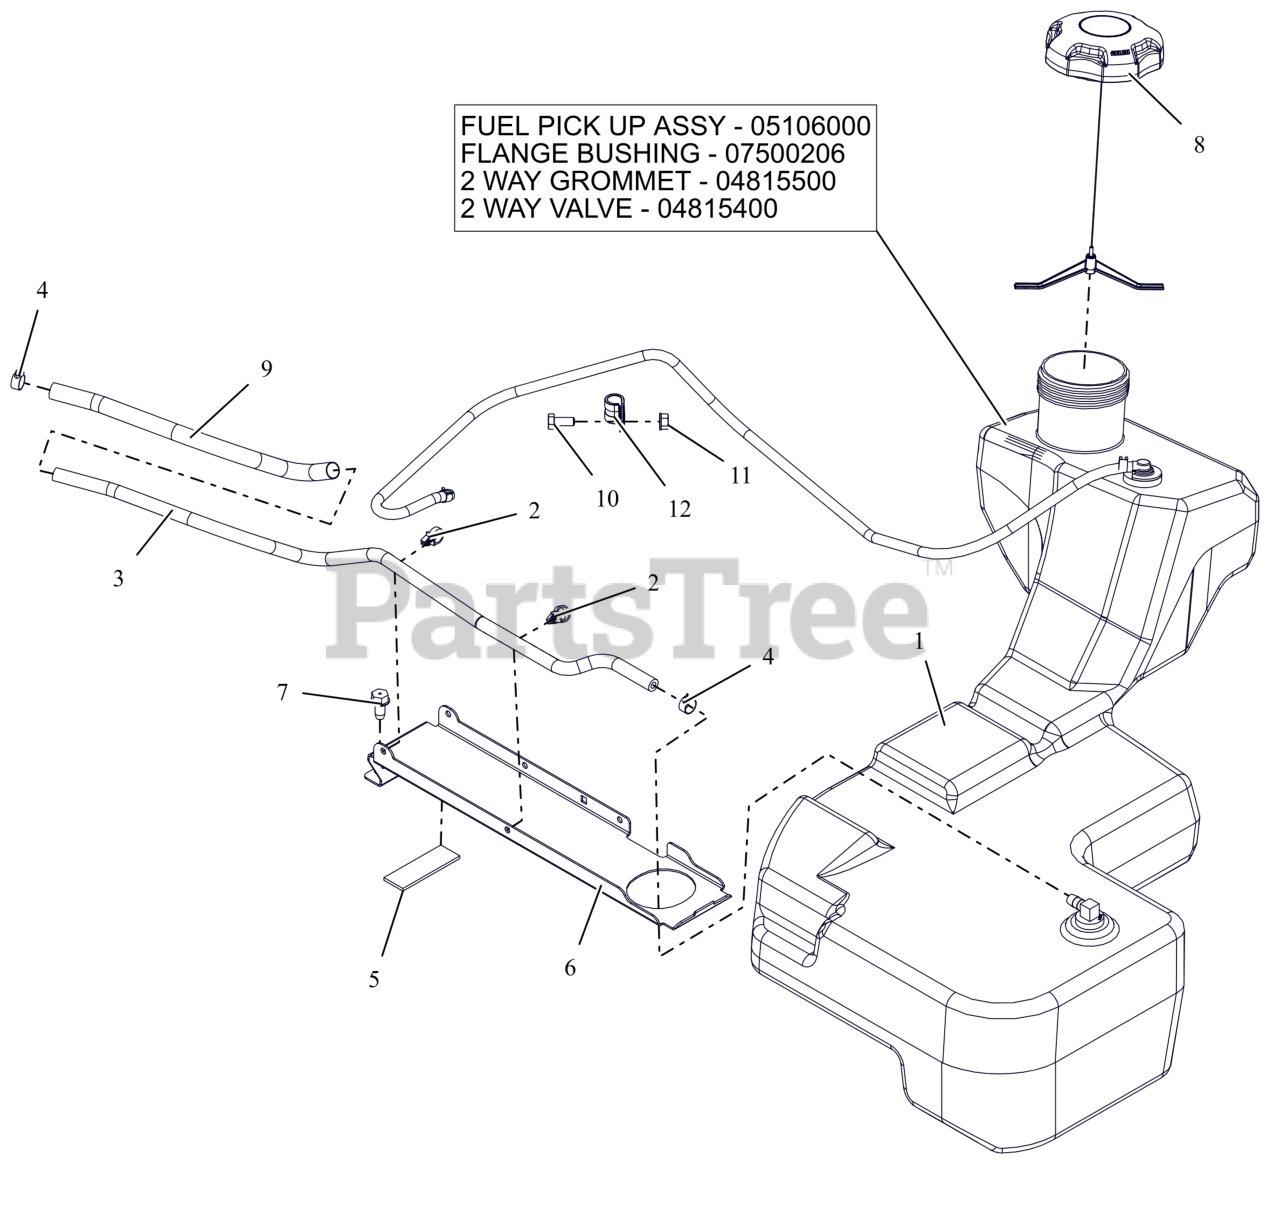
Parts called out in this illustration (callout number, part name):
1	ASM, FUEL TANK-HD
1	ASM, HD FUEL PICK-UP
1	BSHG-FLG .375X1.062X.625 NITR
1	GROMMET, 2-WAY
1	VALVE, 2-WAY
2	ROUTING CLIP (1/2" ID)
3	HOSE, .25 LOW-PERM BULK GAS
4	CLAMP, FUEL LINE
5	PAD,RBR 1.0"X3.0" W/ADHESIVE
6	BRKT, FUEL TANK HOLD DOWN
7	SCR,TAP .375-16X.75 HWH TR ZCC
8	CAP, FUEL - 3.50 RATCHET INLET VENT
9	SLEEVE, THERMAL 12"
10	BLT,HEX .31-18X.75 G5 ZCC
11	NUT,LK-CTR-FLG .31-18 GF ZCC
12	CLAMP, CUSHIONED STEEL
